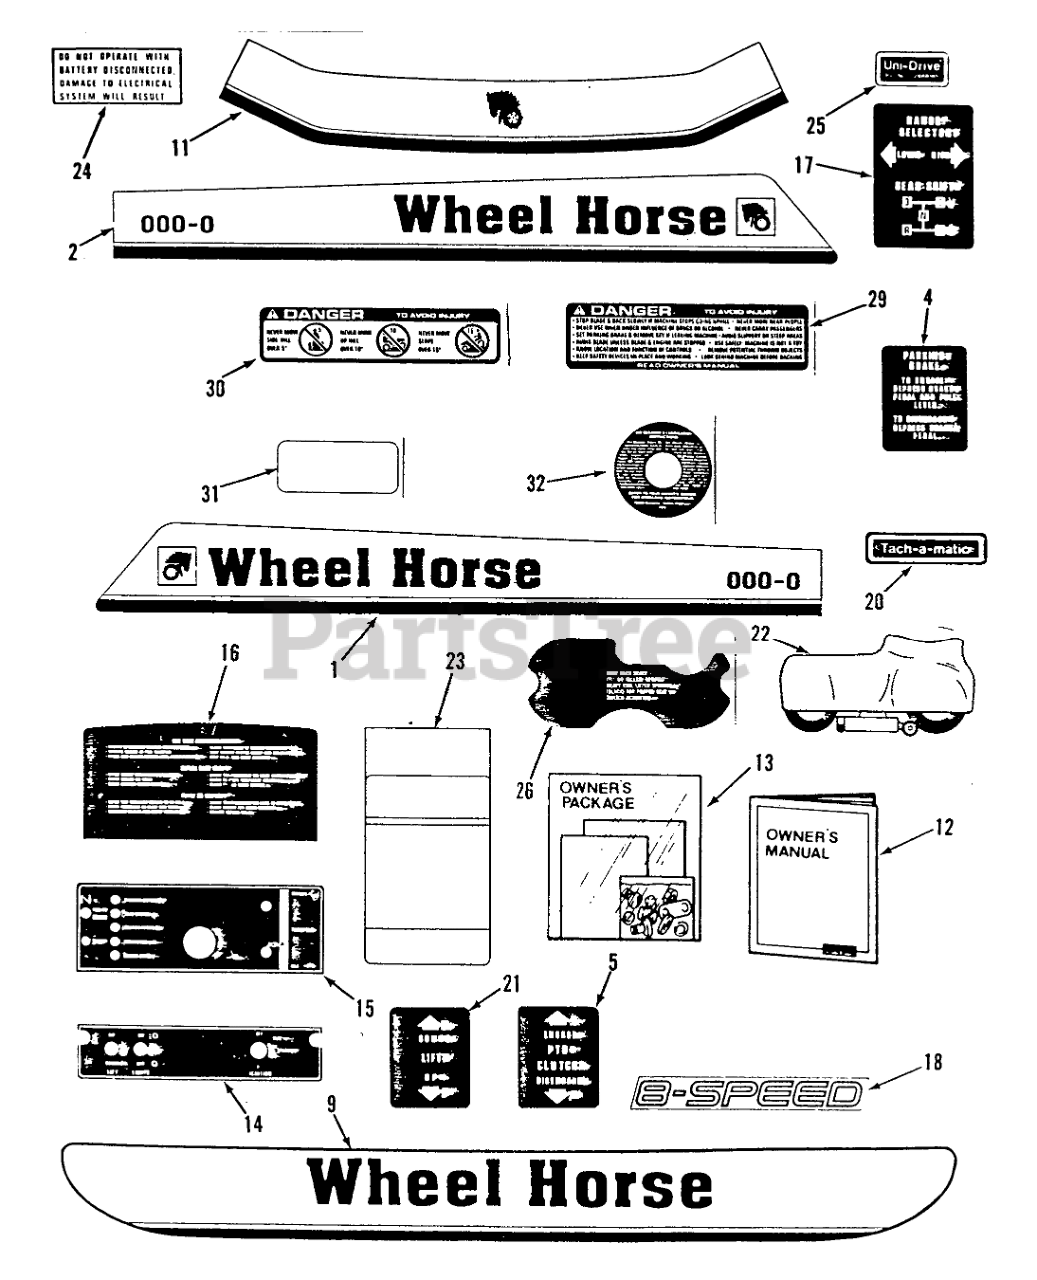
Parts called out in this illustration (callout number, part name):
1	Decal-Hood RH 312 Only
2	Decal-Hood LH 312 Only
4	DECAL-PARKING, BRAKE
5	DECAL PTO CLUTCH
9	Decal-Rear Fender
11	Decal-Hood Front
12	Owners Manual-Tractor
14	DECAL BACK PLATE
15	Decal-Lower Dash 416
16	Decal-Rear Hood
17	DECAL-SHIFT PATTERN
18	DECAL 8SPD
19	DECAL AUTOMATIC
20	DECAL-TACHAMATIC
21	DECAL-LIFT
22	Vinyl Tractor Cover
23	Decal-Maintenance
24	DECAL ELECT SYSTEM
25	Decal-Unidrive
26	DECAL-SEAT LIFTER
29	Decal-Danger
30	Decal-Danger
31	DECAL-OVERLAY
32	Decal-Air Cleaner
